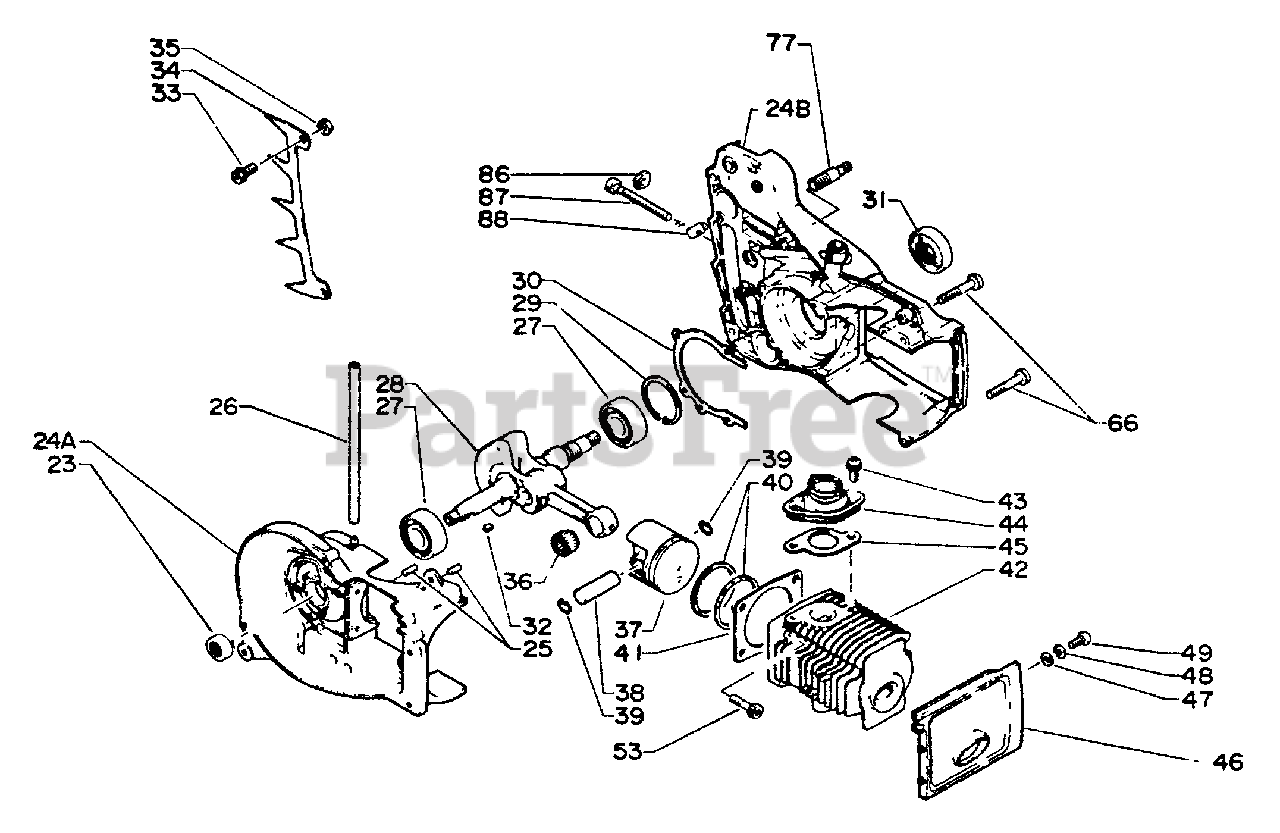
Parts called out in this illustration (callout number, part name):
23	SEAL, OIL
24	CRANKCASE KIT
25	PIN - LOCATING
26	PIPE - 3X6X135 -- BLACK
27	BEARING, BALL - 6202
28	CRANKSHAFT ASSY
29	RING, RETAINING - 35
30	GASKET, CRANKCASE
31	SEAL, OIL
32	SPACER, PISTON
33	SCREW - 5X12
34	SPIKE
35	LOCKNUT - 5
36	BEARING, NEEDLE
37	PISTON
38	PIN, PISTON
39	RING, RETAINING - 8
40	RING, PISTON
41	GASKET, CYLINDER
42	CYLINDER
43	SCREW - 5X10
44	ADAPTOR, INTAKE
45	GASKET, INTAKE
46	COVER, CYLINDER
47	WASHER - 4
48	LOCKWASHER - 4
49	SCREW - 4X12
53	SCREW - 5X20
66	SCREW - 5X30
77	STUD, GUIDE BAR
87	SCREW, TENSIONER
88	TENSIONER, CHAIN
